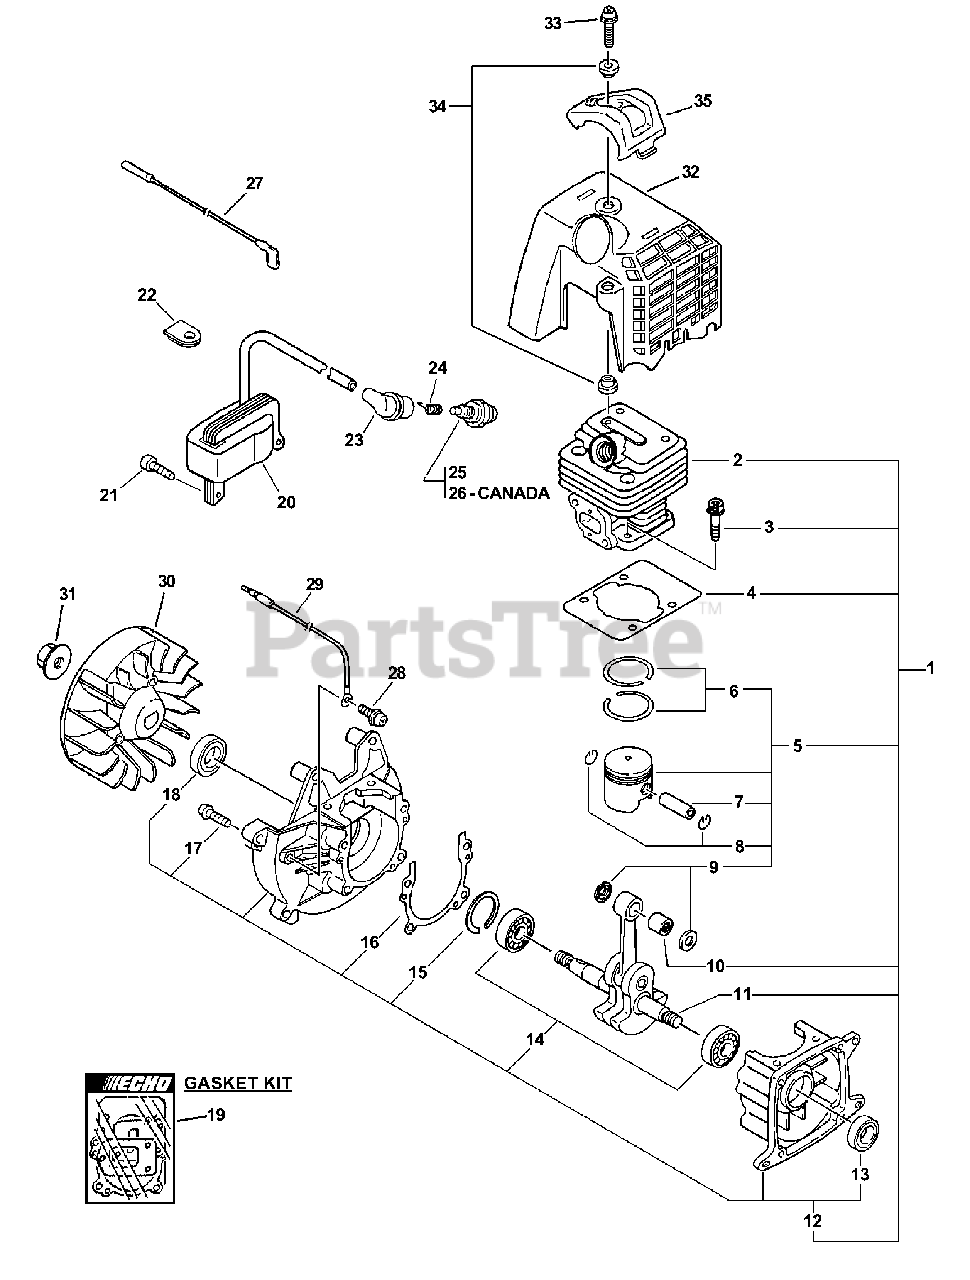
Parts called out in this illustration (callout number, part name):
1	SHORT BLOCK
2	CYLINDER
3	BOLT 5×22
4	GASKET, CYLINDER
5	PISTON KIT
6	RING, PISTON
7	PIN, PISTON 8
8	RING, SNAP
9	WASHER, THRUST
10	BEARING, NEEDLE 8
11	CRANKSHAFT ASSY
12	CRANKCASE KIT
13	SEAL, OIL 12
14	BEARING, BALL 6001
15	RING, SNAP 28
16	GASKET, CRANKCASE
17	BOLT 5×25
18	SEAL, OIL 12
19	GASKET KIT
20	COIL, IGNITION
21	BOLT 5×16
23	CAP, SPARK PLUG
24	TERMINAL, SPARK PLUG
25	SPARK PLUG - BPM-7Y
26	SPARK PLUG - BPMR7A
27	LEAD - IGNITION 145 MM
28	SCREW 5×10
29	LEAD - GROUND
30	FLYWHEEL
31	NUT, FLANGE M8
32	COVER, ENGINE - ORANGE
33	BOLT 5×16
34	COLLAR 5
35	GUARD, TOP
